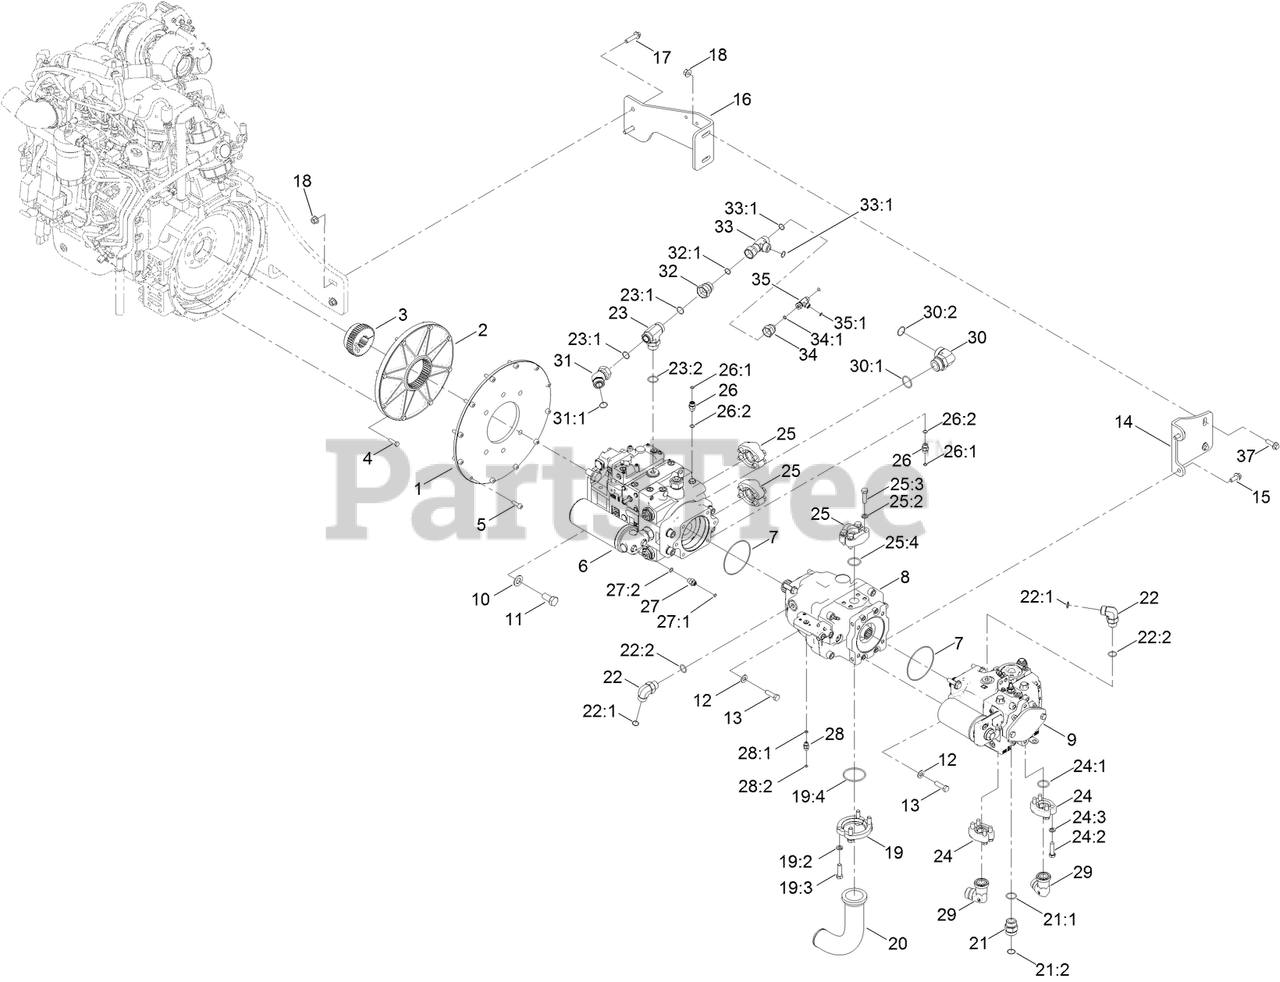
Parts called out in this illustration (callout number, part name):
1	PLATE-MOUNT, PUMP
2	COUPLING-DRIVE, NYLON
3	HUB-STEEL, 13T
4	SCREW-HH
5	SCREW-HSH
6	ROTARY PUMP ASM
7	SEAL-O RING
8	LOAD-SENSE PUMP ASM
9	HYDROSTAT PUMP ASM
12	WASHER-FLAT
13	SCREW-HH
14	BRACKET-MOUNTING, PUMP
15	SCREW-HHF
16	BRACKET-MOUNTING, CENTER
17	SCREW-HHF
18	NUT-LOCK, HHF
19	SPLIT FLANGE KIT
19:1	Flange
19:2	WASHER-LOCK
19:3	SCREW-HH
19:4	O-RING
20	TUBE-BENT
21	FITTING-STRAIGHT
21:1	O-RING
21:2	O-RING
22	FITTING-ELBOW-90
22:1	O-RING
22:2	O-RING
23	FITTING-HYD
23:1	O-RING
23:2	O-RING
24	FLANGE KIT
24:1	O-RING
24:2	SCREW-HH
24:3	WASHER-LOCK
25	SPLIT FLANGE KIT
25:1	FLANGE-HALF
25:2	WASHER-LOCK
25:3	SCREW-HH
25:4	O-RING
26	FITTING-STRAIGHT
26:1	O-RING
26:2	O-RING
27	FITTING-STRAIGHT
27:1	O-RING
27:2	O-RING
28	FITTING-STRAIGHT
28:1	O-RING
28:2	O-RING
29	ELBOW-90
30	FITTING-ELBOW 90
30:1	O-RING
30:2	O-RING
31	FITTING-ELBOW, 45
31:1	O-RING
32	FITTING-REDUCER
32:1	O-RING
33	FITTING-TEE
33:1	O-RING
34	FITTING-REDUCER
34:1	O-RING
35	FITTING-TEE, SWIVEL NUT
35:1	O-RING
37	SCREW-HHF
